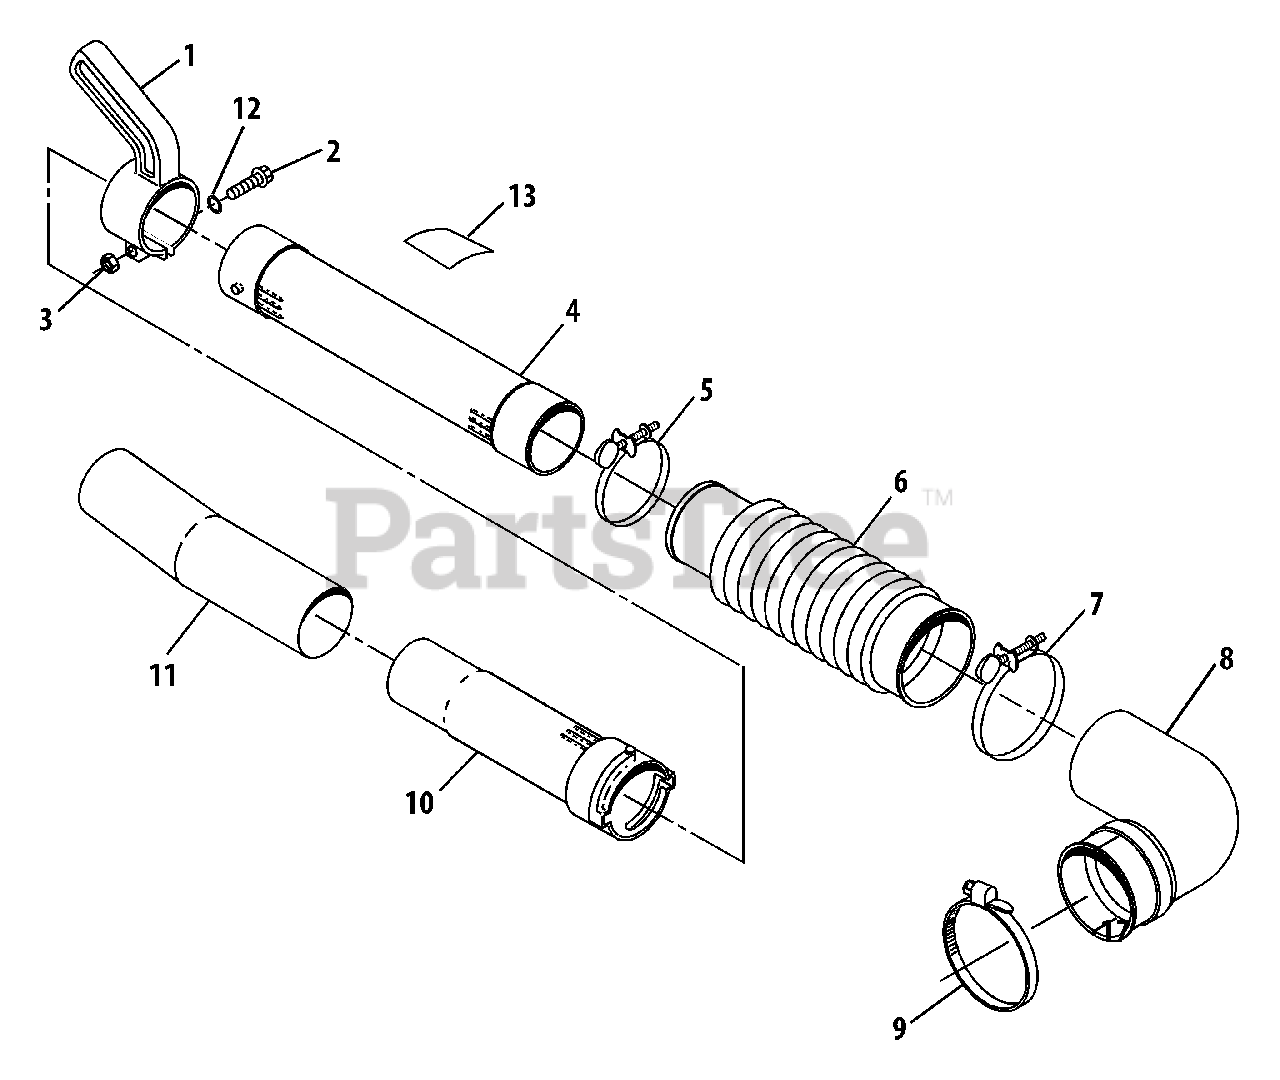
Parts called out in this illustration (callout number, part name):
1	HANDLE
2	BOLT
3	NUT, HEX M6
4	TUBE, BLOWER - SWIVEL
5	CLAMP
6	TUBE, BLOWER - FLEXIBLE
7	CLAMP
8	TUBE, BLOWER - ELBOW
9	CLAMP
10	TUBE, BLOWER - EXTENSION
11	TUBE, BLOWER - ROUND NOZZLE
12	WASHER 6.5×11.5×0.8
13	LABEL, EB501
